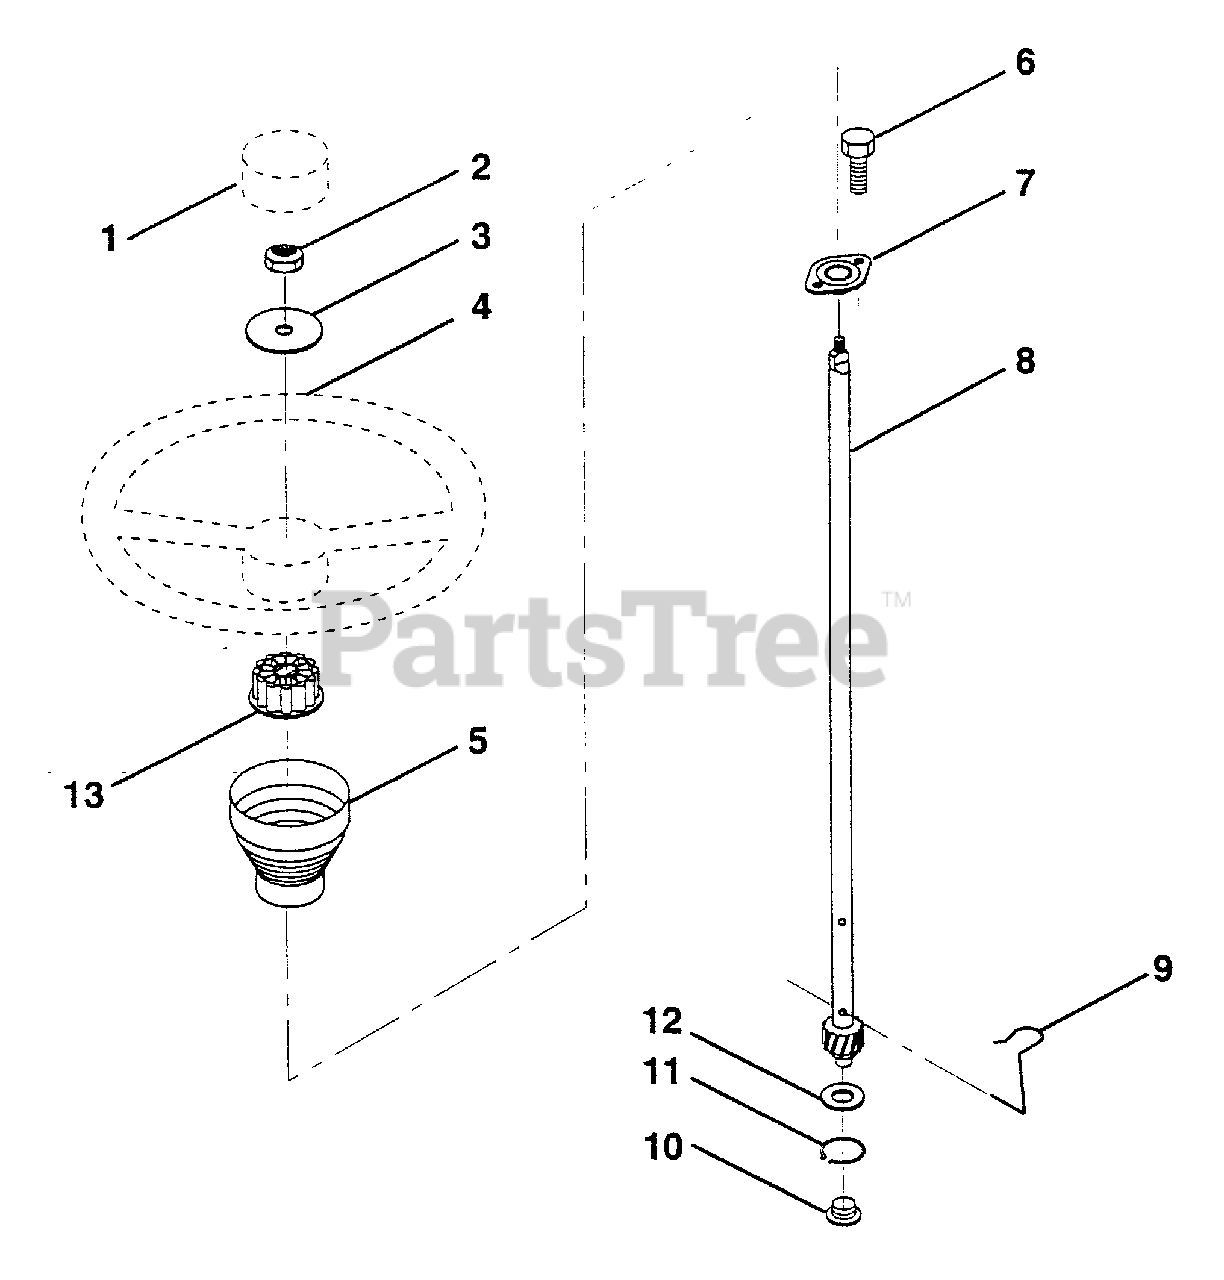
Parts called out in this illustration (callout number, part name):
1	Insert, Steering Wheel
2	Locknut 3/8-24 UNF
3	Washer 12/32 x 2-3/8 x 8 Gauge
4	Steering Wheel
5	Sleeve, Steering
6	Screw, Hex Head #10-16 x 1/2
7	Bushing, Steering
8	Shaft, Steering
9	Clip, Steering
10	Bushing, Lower, Steering
11	Ring, Retaining
12	Washer 21/32 x 1 x 16 Gauge
13	Adaptor, Steering Wheel
